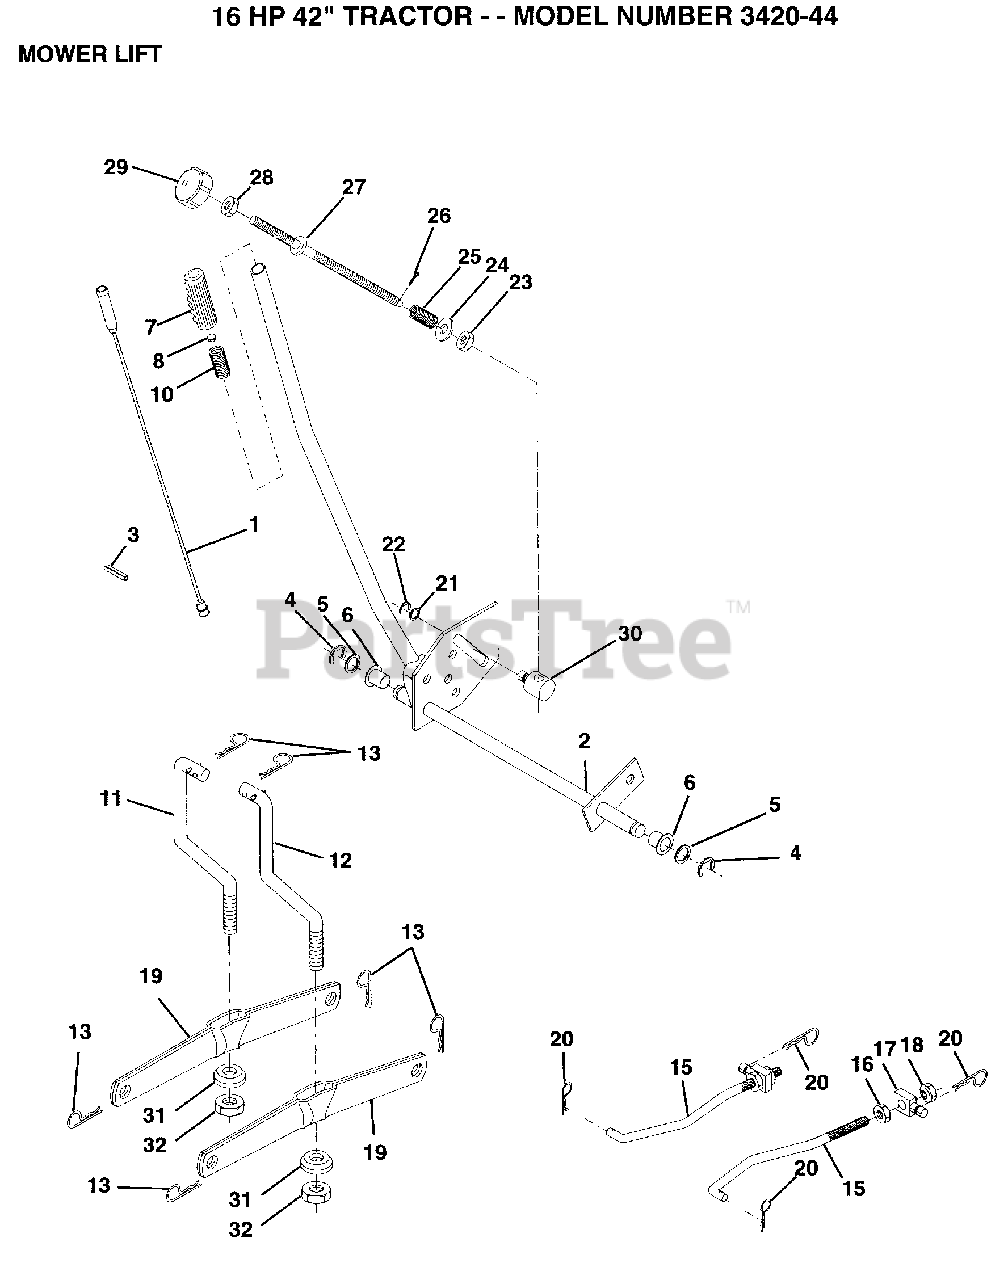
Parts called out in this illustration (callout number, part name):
1	WIRE ASM
2	SHAFT.ASM.LIFT LH
3	PIN GROOVE
5	WASHER
6	NYLON BEARING
7	GRIP
15	LINK.FRONT
16	NUT
17	TRUNION
18	NUT.LK.W/WSH.1/2.
19	ARM SUSP REAR
20	RETAINER.SPRING
21	WASHER
22	KLIP RING
23	NUT T
24	WASHER
25	SPRING T
27	ROD LIFT LT
28	NUT
29	KNOB INF 3/8-16
30	TRUNION LT
31	BEARING PVT LH
32	NUT.LOCK.3/8-24
